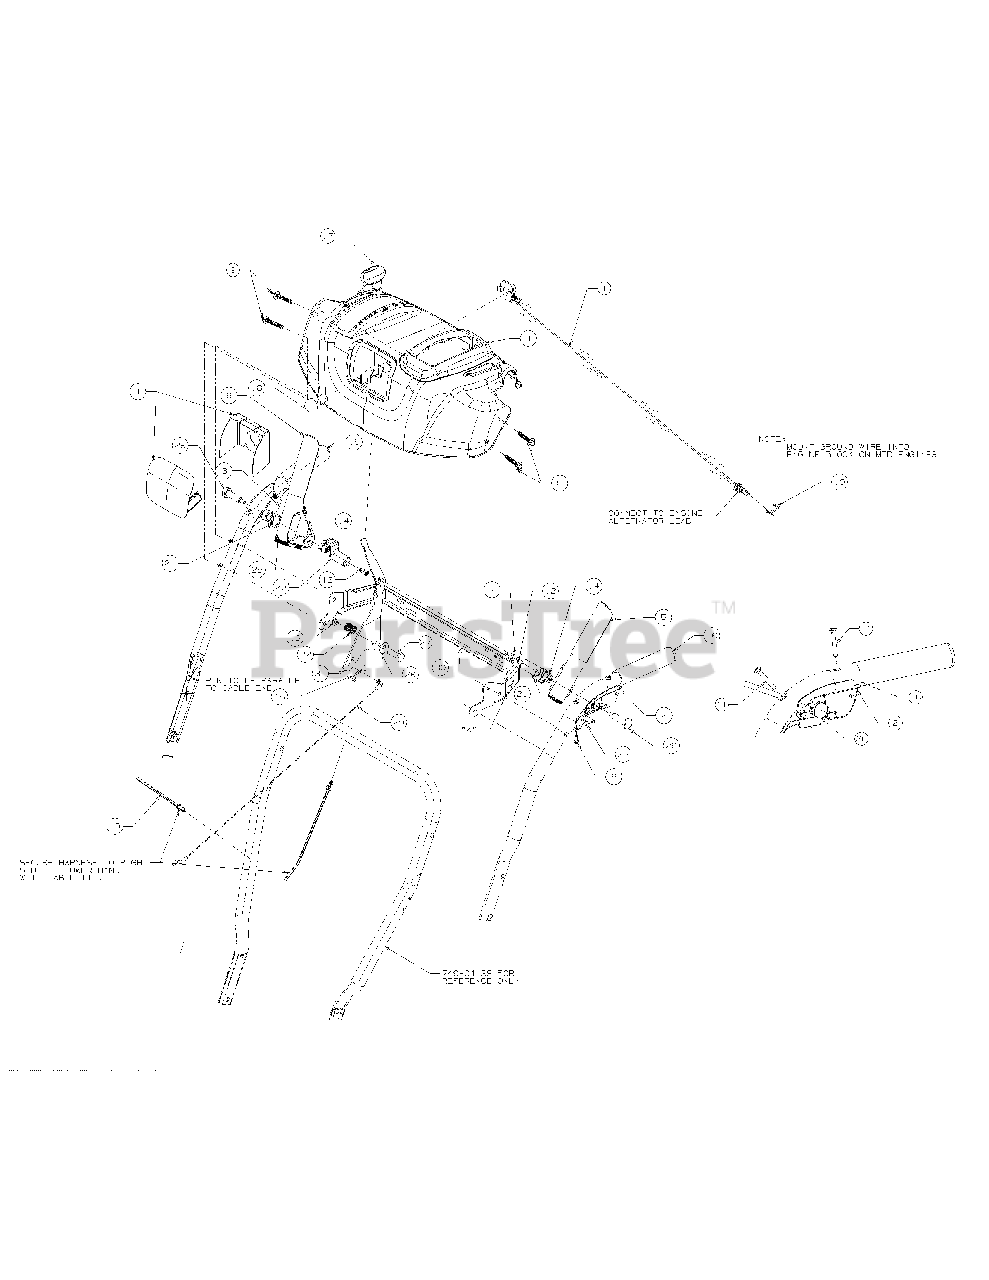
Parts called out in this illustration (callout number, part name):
1	Harness Assy-Li
2	Handle Assy-Clutch
3	Handle-Clutch Lock
4	Panel Asm:Handl
5	Handle Assy-Engage
6	Handle Asm-Engage
7	Rod-Pivot
8	Screw-Plastite
10	Screw-Hex Wash Sf
11	Screw-Oval C-Sunk
12	Screw-Hex Socket H
13	Nut-Flglk
14	Nut-Hex W/Patch
15	Pin-Intern Cot
17	Knob-Shift
18	Lamp-12 Volt 114
19	Tie-Push Mount
20	Plate-Lock
21	Cam-Clutch Lock
22	Spring-Compression
23	Spring-Clutch Lock
24	Spring-Torsion
25	Rubber Bumper
26	Washer-Fl .40X.8
27	Screw-Shoulder
28	Screw-Shoulder .43
29	Cable-Speed Se
31	Lever-Shift
